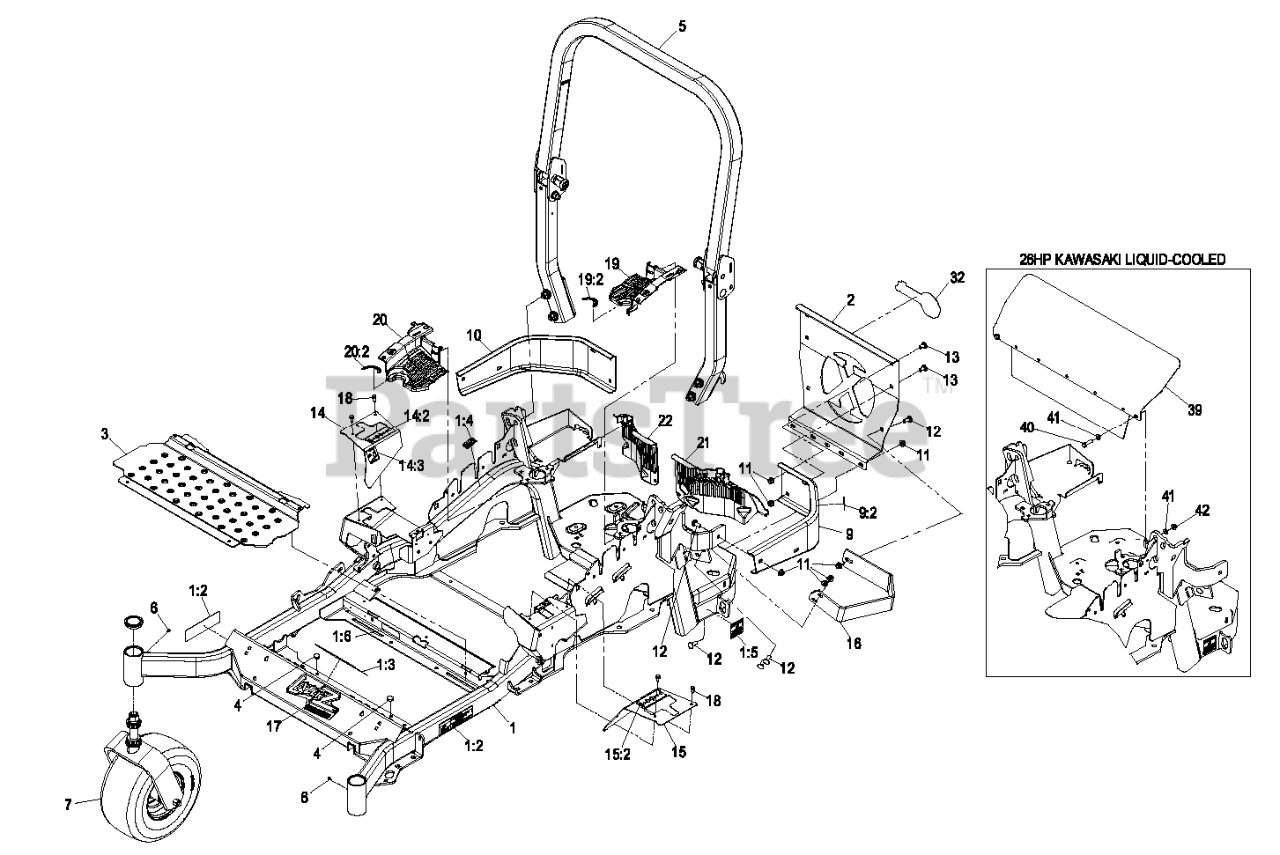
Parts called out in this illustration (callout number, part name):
1	MAIN FRAME ASM
1:2	DECAL-WARNING
1:3	DECAL-WARNING
1:4	DECAL-CAUTION
1:5	DECAL-BELT DRIVE
1:6	DECAL-ARRESTER, SPARK
2	PLATE,REAR GUARD
5	ASM,ROPS SERVICE EXMARK
9	LH BUMPER ASM
9:2	DECAL-CAUTION
10	BUMPER-RH
11	NUT-HF, NI
12	SCREW-CARR
13	SCREW-CARR
14:2	DECAL-MOTION CONTROL
15	LH MOTION CONTROL COVER ASM
15:2	DECAL-MOTION CONTROL
17	DECAL,LAZER AS LOGO
18	SCREW-HWH
19	LH HYDRO GUARD ASM
19:2	DECAL-HYDRO OIL
20	RH HYDRO GUARD ASM
20:2	DECAL-HYDRO OIL
21	GUARD-HYDRO, REAR (LH)
22	GUARD-HYDRO, REAR (RH)
39	ASM,AIR DEFLECTOR
40	SCREW-HH
41	WASHER-SPRING
42	NUT-HF, NI
